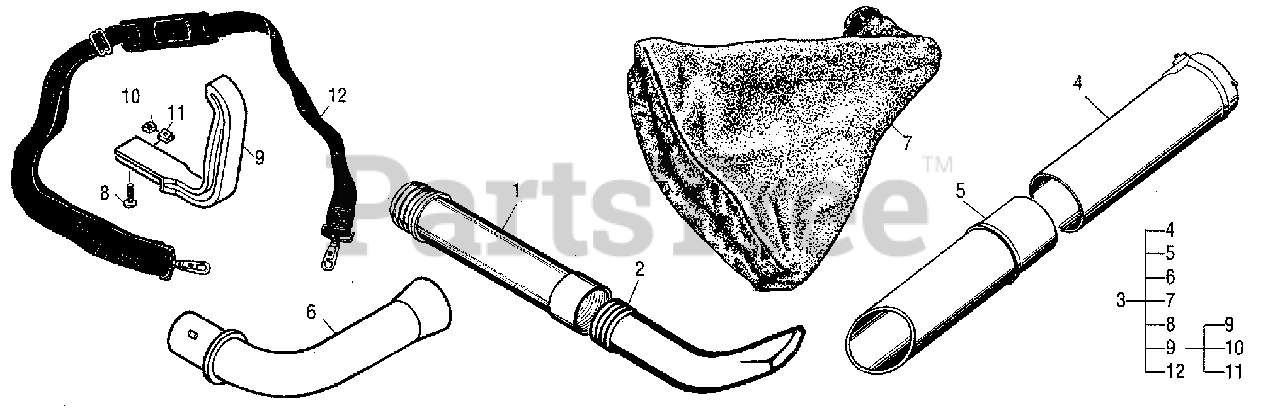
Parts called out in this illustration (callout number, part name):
1	Tube, Blower
2	Nozzle, Fishtail
3	Kit, Vacuum
4	Tube, Suction
5	Tube, Outer
6	Tube, Blower 90 deg
7	Blower Bag Asy
8	Screw, 10-24 x .62 Tr HD Torx
9	Side Handle Asy
10	Nut, Square 10-24
11	Retainer, Nut
